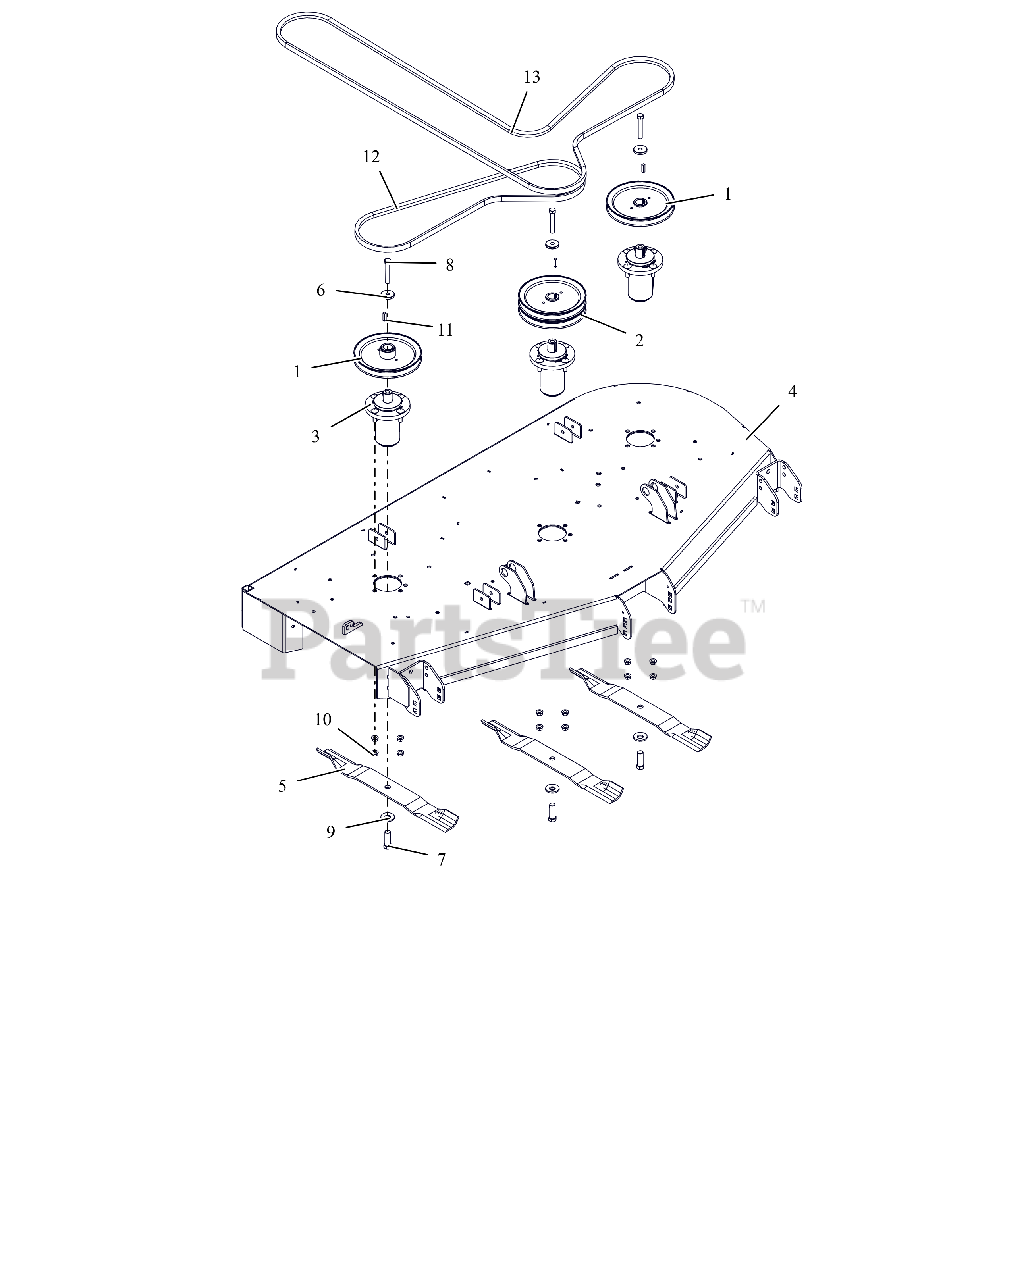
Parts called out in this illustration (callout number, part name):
1	PULLEY, V-7.50 OD X 1"ID
2	PULLEY, DOUBLE 1"X7.50"&7.50" (BLACK)
3	ASM, MAINT FREE ALUM SPINDLE
4	KIT,DECK-60" W/DECALS-GRAVELY
5	BLADE, 20.5"
6	RETAINER, SHEAVE
7	BLT, HEX .62-18X1.75 G8 ZCC
8	BLT, HEX .38-16X2.75 G8 ZCC
9	WSHR-BLVL .669X1.535X.138
10	NUT-LK-CTR-FLG .375-16 GF ZCC
11	KEY, SQ .25X.25X1.00 RC 40-50
12	V-BELT, B-COGGED
13	V-BELT, HB SECTION
